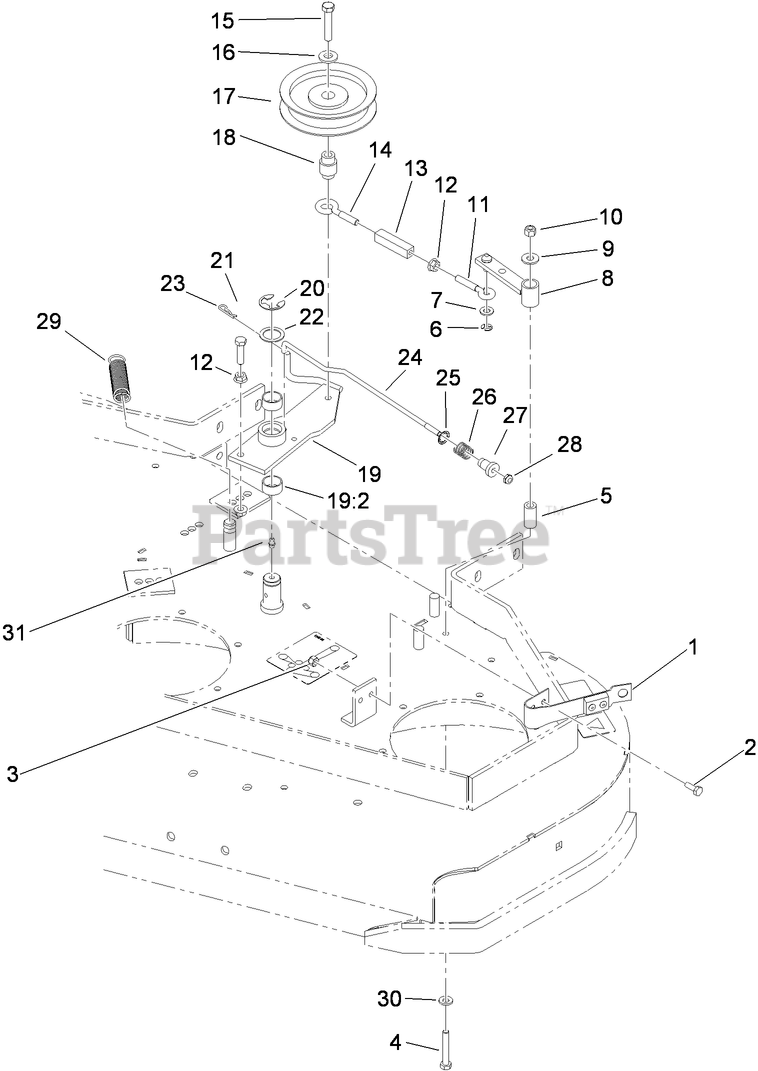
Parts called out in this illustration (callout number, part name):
1	PAD AND SPRING ASM
2	SCREW-HH
3	NUT-LOCK, NI
4	SCREW-HH
5	TUBE-PIVOT
6	RING-RETAINING, EXT
7	WASHER-PLAIN
8	ARM-ASSIST
9	WASHER-FLAT
10	NUT-LOCK, NI
11	EYEBOLT-THREAD, RH
12	NUT-HF
13	BODY-TURNBUCKLE
14	EYEBOLT-THREAD, LH
15	SCREW-HH
16	WASHER-BELLEVILLE
17	PULLEY-IDLER
18	BUSHING-ENGAGEMENT
19	Idler Arm ASM
19:2	SLEEVE-BEARING
20	RING-RETAINING, EXT
21	SCREW-HH
22	WASHER-SPINDLE
23	PIN-COTTER
24	ROD-BRAKE
25	RING-PUSH ON
26	SPRING-COMPRESSION
27	SPACER-FLANGED
28	NUT-LOCK, NI
29	SPRING-EXTENSION
30	WASHER-SPRING
31	FITTING-GREASE
